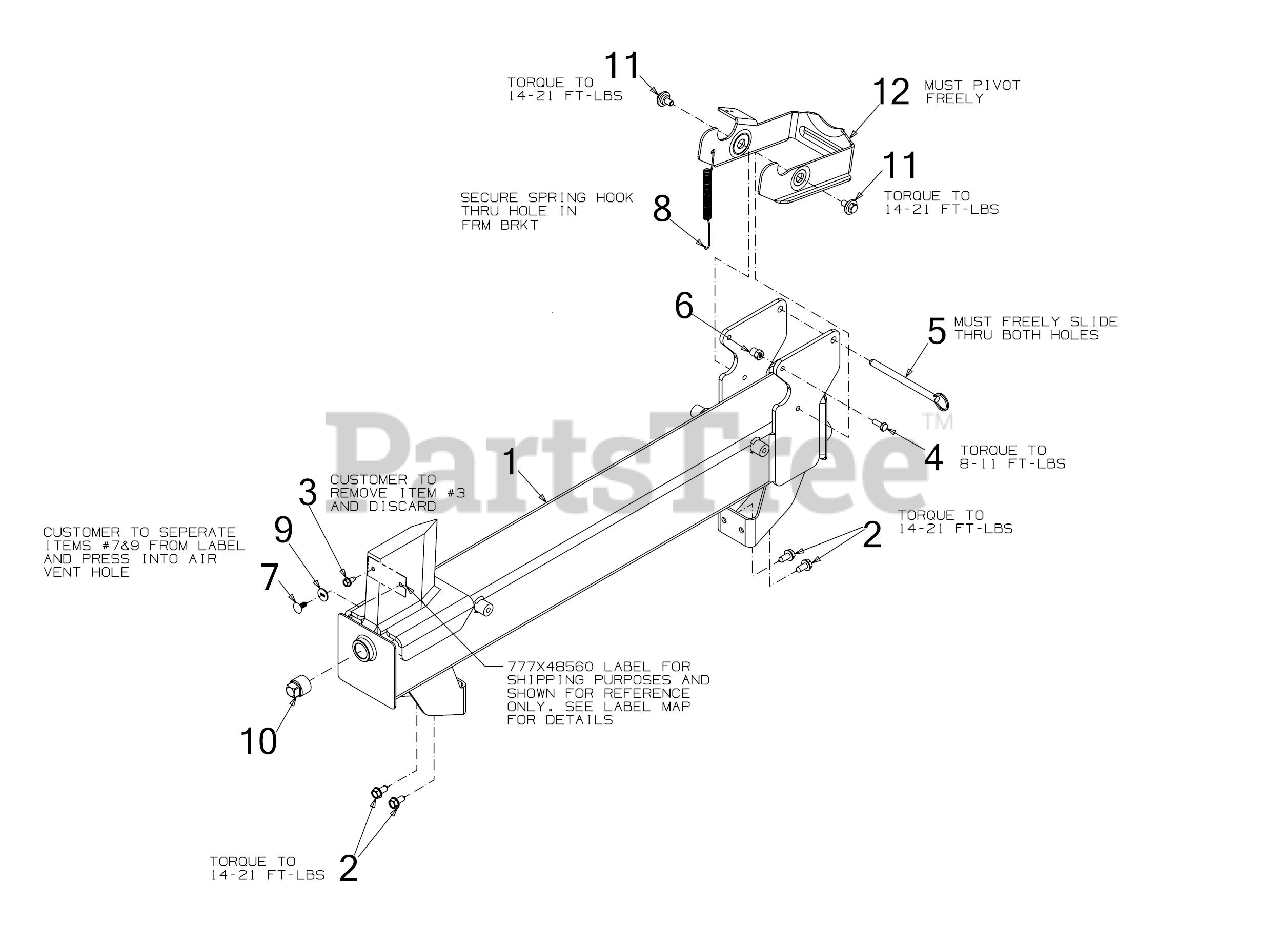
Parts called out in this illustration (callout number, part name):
1	TANK ASSEMBLY
2	SCREW 5/16-18 x .750
3	SCREW 1/4-20 X.500
4	SCREW 1/4-20 x .750 GR8
5	DETENT CLEVIS PIN .375
6	HEX NUT W/PATCH
7	RATCHET CLIP .250
8	REVERSE RETURN SPRING
9	FELT SLOTTED WASHER 3/4 OD
10	PIPE PLUG
11	SHOULDER SCREW .560X.165: 5/16-18
12	LOCK CYLINDER BRACKET
